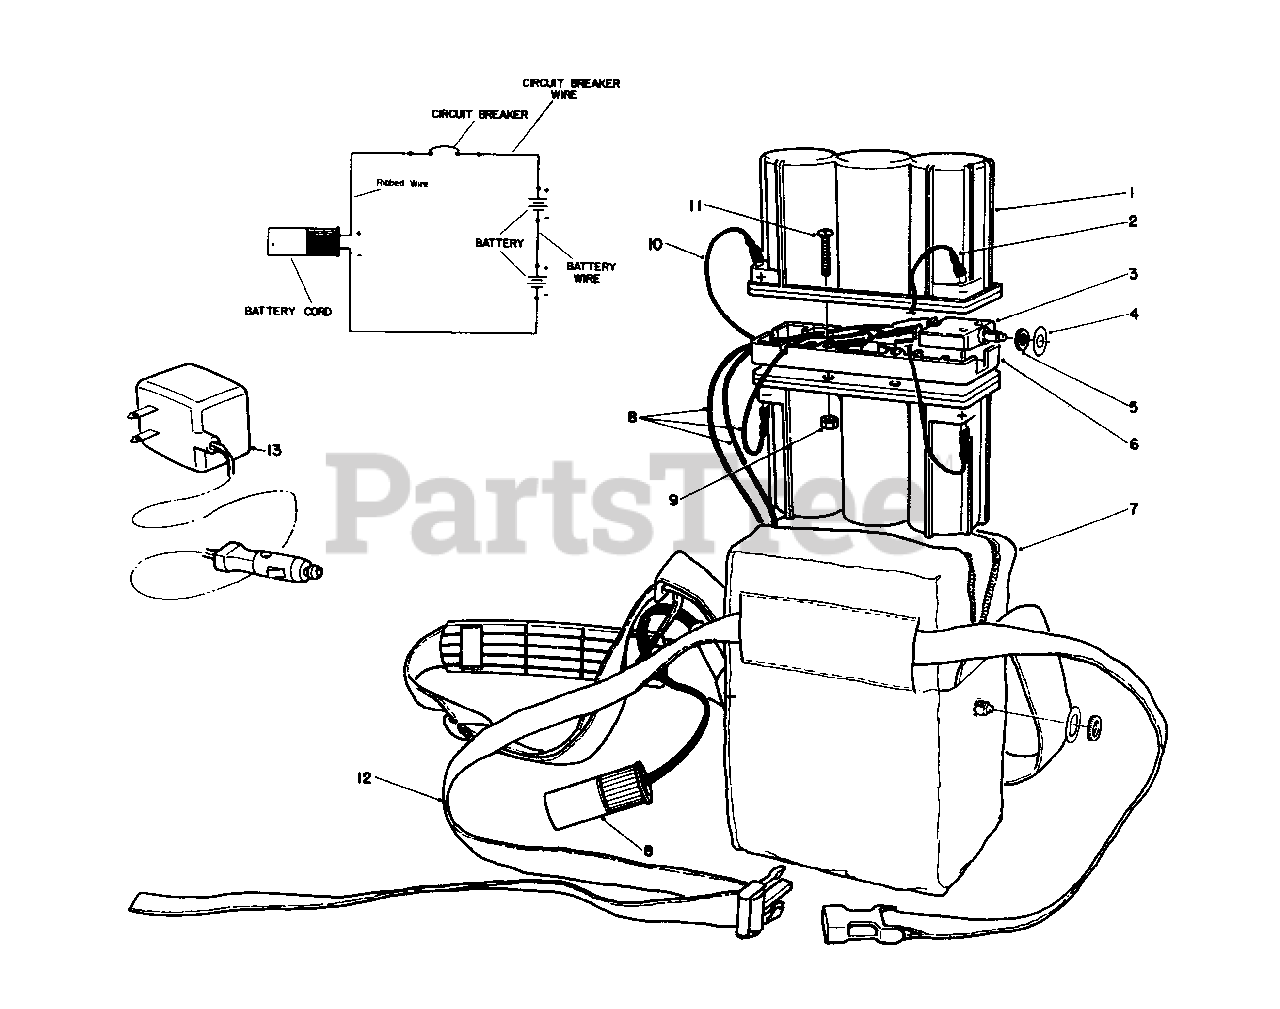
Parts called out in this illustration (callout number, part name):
1	Battery-6 Volt
2	Wire-Battery
3	Circuit Breaker
4	Plate-Breaker, Circut
5	Nut-Knurled
6	Spacer-Battery
7	Pack-Soft
8	Cord-Battery
10	Wire-Breaker, Circuit
11	Screw-Phillips, Pan Hd.
13	Charger-12 Volt
